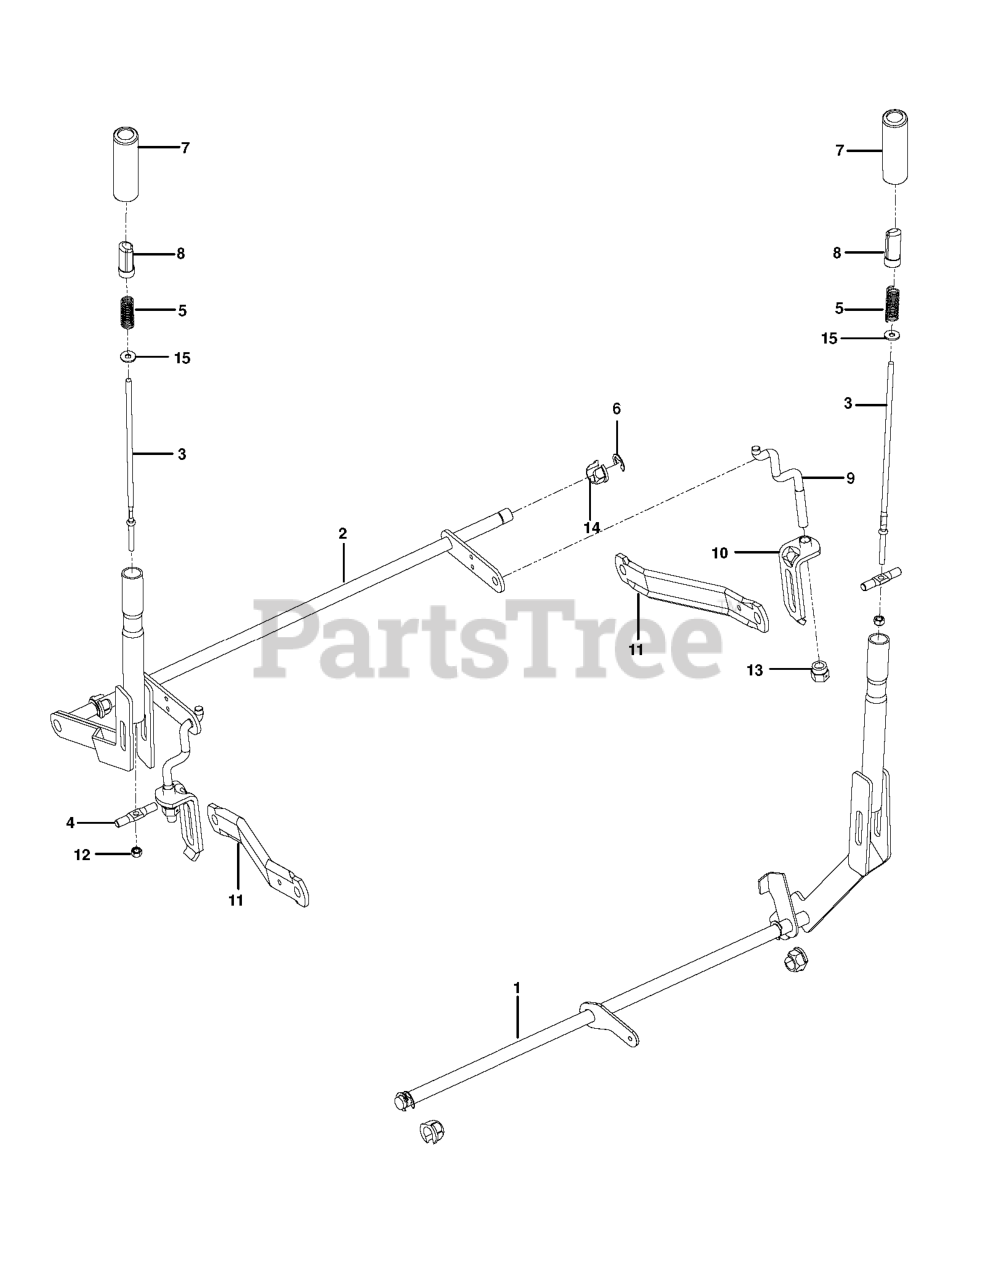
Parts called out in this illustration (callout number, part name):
1	SUBASM.SHAFT.BRAKE.WLDMNT.MED
2	SHAFT.LIFT.MED.BLACK
3	ROD, HANDLE RELEASE
4	RB ROD, LATCH RELEASE
5	SPRING, COMPRESSION
6	E-RING 5/8
7	GRIP, HANDLE, BLACK 4"
8	BUTTON, PUSH, BLACK
9	LINK, REAR SUSPENSION
10	ASSEMBLY, BRKT LINK
11	ARM.SUSPENSION.MOWER
12	LOCKNUT.NYLOC.1/4-20
13	NUT, LIFT LINK 7/16-20
14	PLASTIC NUT
15	WASHER PM
